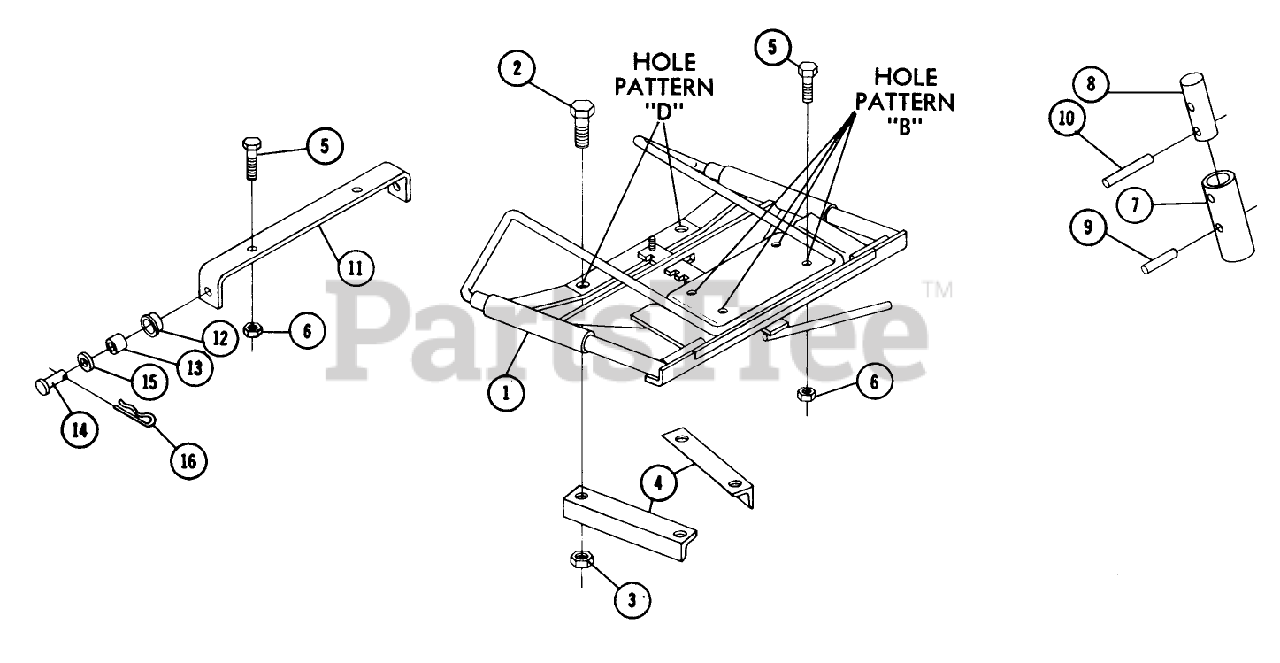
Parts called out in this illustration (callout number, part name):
1	Torsion Bar Adjuster
2	Bolt Hex 1/2-13 x 1
3	Locknut-1/2-13
4	Angle
5	Bolt 3/8-16 x 3/4
8	Adapter-Steering Wheel
9	PIN-ROLL 1/4 X 1 1/4
10	Pin-Roll
11	Bracket
12	BUSHING-FLANGED
13	SPACER
15	Washer
16	Hairpin
